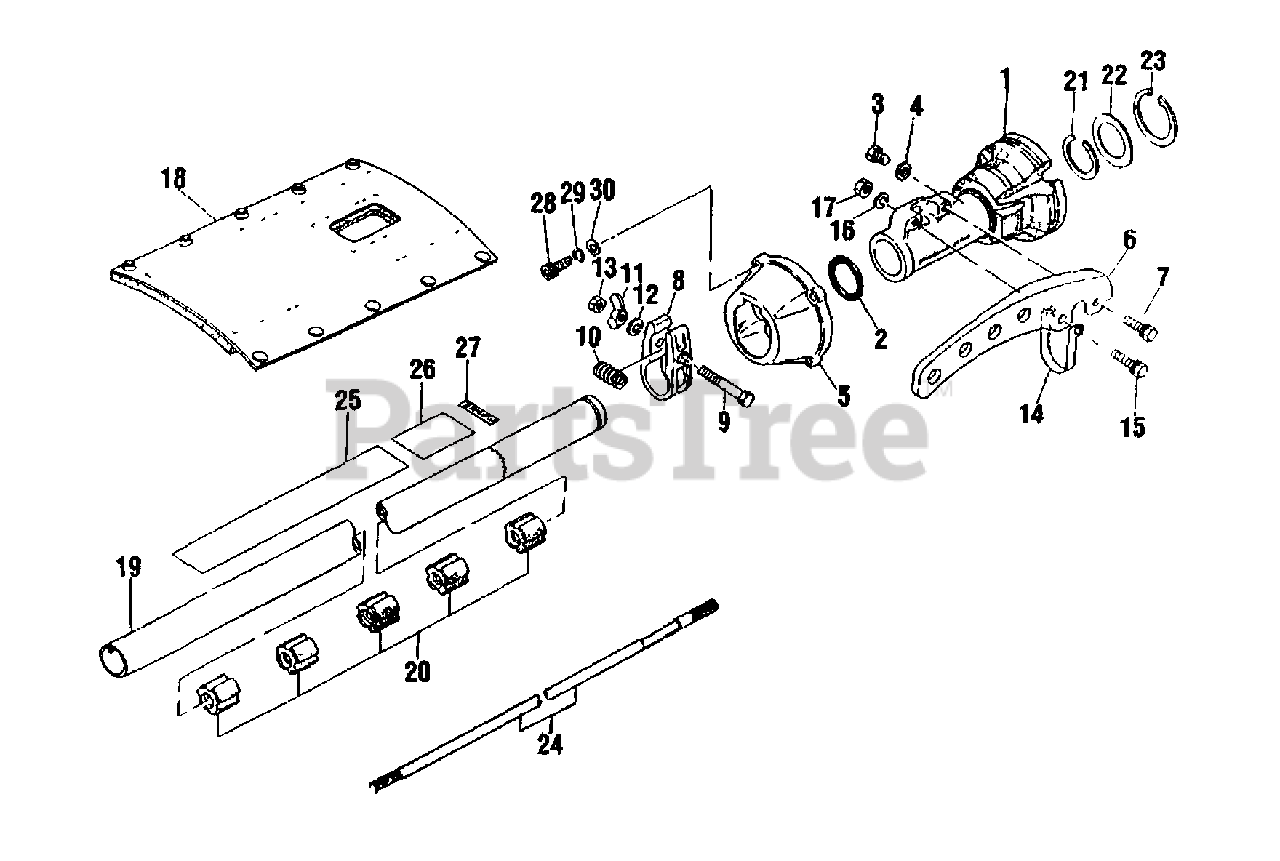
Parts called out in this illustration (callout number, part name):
1	SWIVEL JOINT
2	O-RING
3	BOLT - 6X8
4	WASHER
5	CONNECTOR, CAP
7	BOLT - 6X16
8	SWIVEL LOCK
9	BOLT
10	SPRING
11	WINGNUT
12	WASHER - 6
13	LOCKNUT - 6
14	CLAMP
15	BOLT - 6X30
16	LOCKWASHER - 6
17	NUT - 6
18	PROTECTOR
19	PIPE - OUTER
20	BUSHING
21	RING, RETAINING
22	STOPPER
23	RING, RETAINING - 40
24	PIPE, MAIN
25	LABEL - MODEL
26	LABEL - CAUTION
27	LABEL - ALIGNMENT
28	SCREW - 5X20
29	LOCKWASHER - 5
30	WASHER - 5
